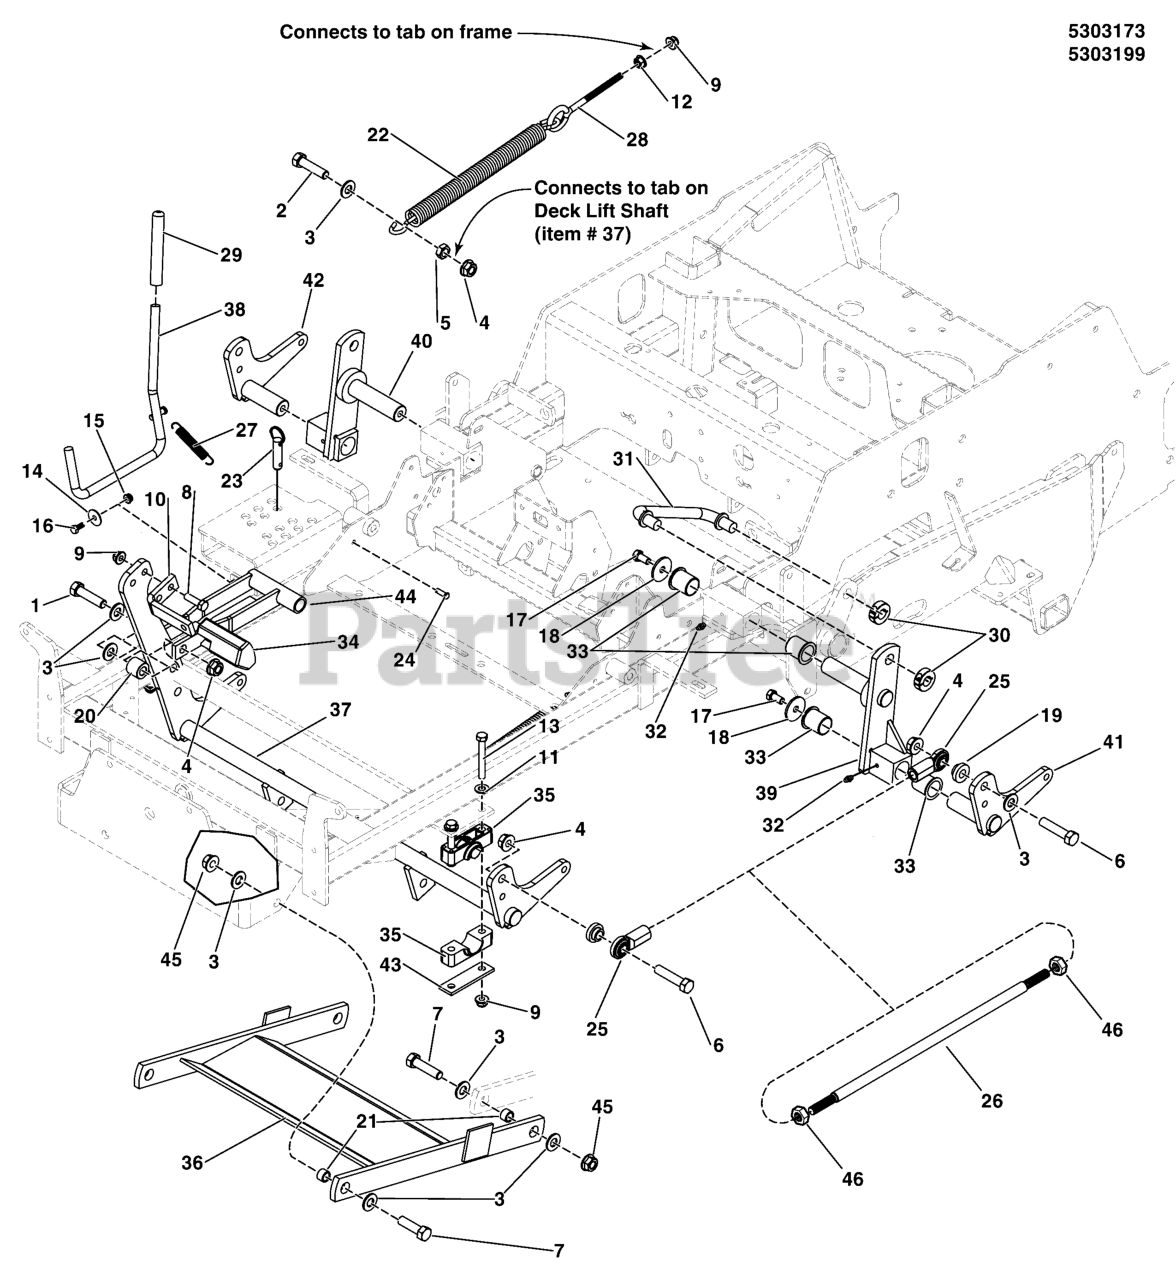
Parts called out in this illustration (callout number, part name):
1	BOLT, 1/2-13 X 2-3/4 GD5 CZ
2	BOLT, 1/2-13 X 2" GD5 CZ
3	WASHER, 1/2 SAE
4	NUT, Hex Flange, Nylock, 1/2-13
5	NUT, 1/2-13 HEX JAM
6	BOLT, 1/2-13 X 2-1/4" GD5 CZ
7	BOLT, 1/2-20 X 1-3/4" GD8 CZ
8	BOLT, 3/8-16 X 1-1/4" GD5 CZ
9	NUT, 3/8-16 HEX NYLOCK FLANGE
10	PEDAL, FOOT - BLK
11	WASHER, 3/8 SAE
12	NUT, 3/8-16 HEX SERRATED FLANGE
13	BOLT, 3/8-16 X 2-3/4" GD5 CZ
14	WASHER, 1/4 FENDER
15	NUT, 1/4-20 HEX NYLOCK FLANGE
16	HHCS, 1/4-20 X 0.625, GR5, ZINC/CLEAR
17	BOLT, 3/8-16 X 3/4, PLT W/PATCH
18	WASHER, .390 X 1.50 X .109, YZ
19	SPACER, .52 X 1.00 X .44. CZ
20	SPACER, .52 X 1.00 X .88, CZ
21	INSERT, BEARING
22	SPRING-EXT, 1.00 ODX13.25LGX.177WR, BLK
23	PIN, HITCH, 1/2 X 2.00 OAL, YP
24	CLEVIS PIN, 1/4 X 1/2, CZ
25	JOINT-BALL .500-20 THD .500ID, CLR ZINC
26	ROD, DECK LIFT, 19.25
27	SPRING-EXT, .740 ODX2.025LGX.072WR, BLK
28	EYE BOLT, 3/8-16 X 6, 3.0 THREAD
28	EYEBOLT, 3/8-16 X 4, 2.13THRD, .75EYE, C
29	GRIP, FOAM, .475 X 4.35 X .095
30	COLLAR, 5/8 SPLIT
31	ROD, SUSPENSION LINK, IS700
32	GREASE FITTING, 1/4-28 STRAIGHT
33	BUSHING, 1.00 X 1.13 X 1.38, PLASTIC
34	PEDAL, Rubber
35	PIVOT BLOCK, PLASTIC
36	WELD, PULLER BAR, IS700Z - BLK
37	WELD, DECK LIFT SHAFT, IS700 - RED
38	WELD, Rod, Deck Lift - BLK
39	WELD, REAR LIFT - LH - BLK
40	WELD, REAR LIFT - RH - BLK
41	WELD, DECK LIFT LEVER, LH - BLK
42	WELD, DECK LIFT LEVER, RH - BLK
43	PLATE, PIVOT BLOCK SUPPORT - BLK
45	NUT, Hex, Nylon Lock, 1/2-20
46	NUT, 1/2-20 HEX JAM
